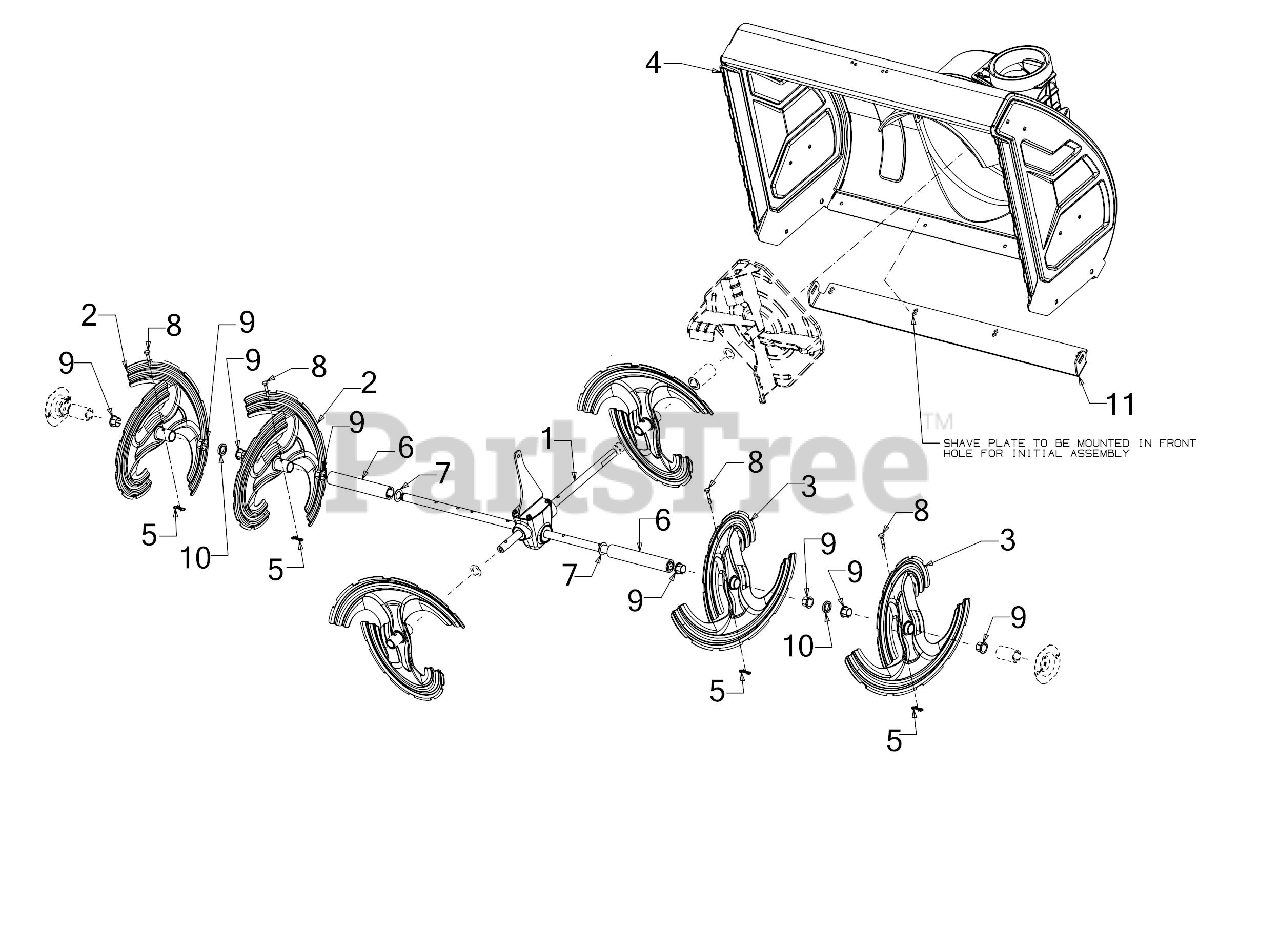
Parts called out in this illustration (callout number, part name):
1	34" AUGER GEARBOX ASSEMBLY
2	14" AUGER SPIRAL ASSEMBLY (RH)
3	14" AUGER SPIRAL ASSEMBLY (LH)
4	34" AUGER HOUSING ASSEMBLY
5	BOW TIE COTTER PIN 1/4-5/16
7	FLAT WASHER .793ID x 1.24OD x .060
8	SHEAR PIN .25 x 1.50 GR2
9	FLANGE BUSHING
11	33.50" SHAVE PLATE
